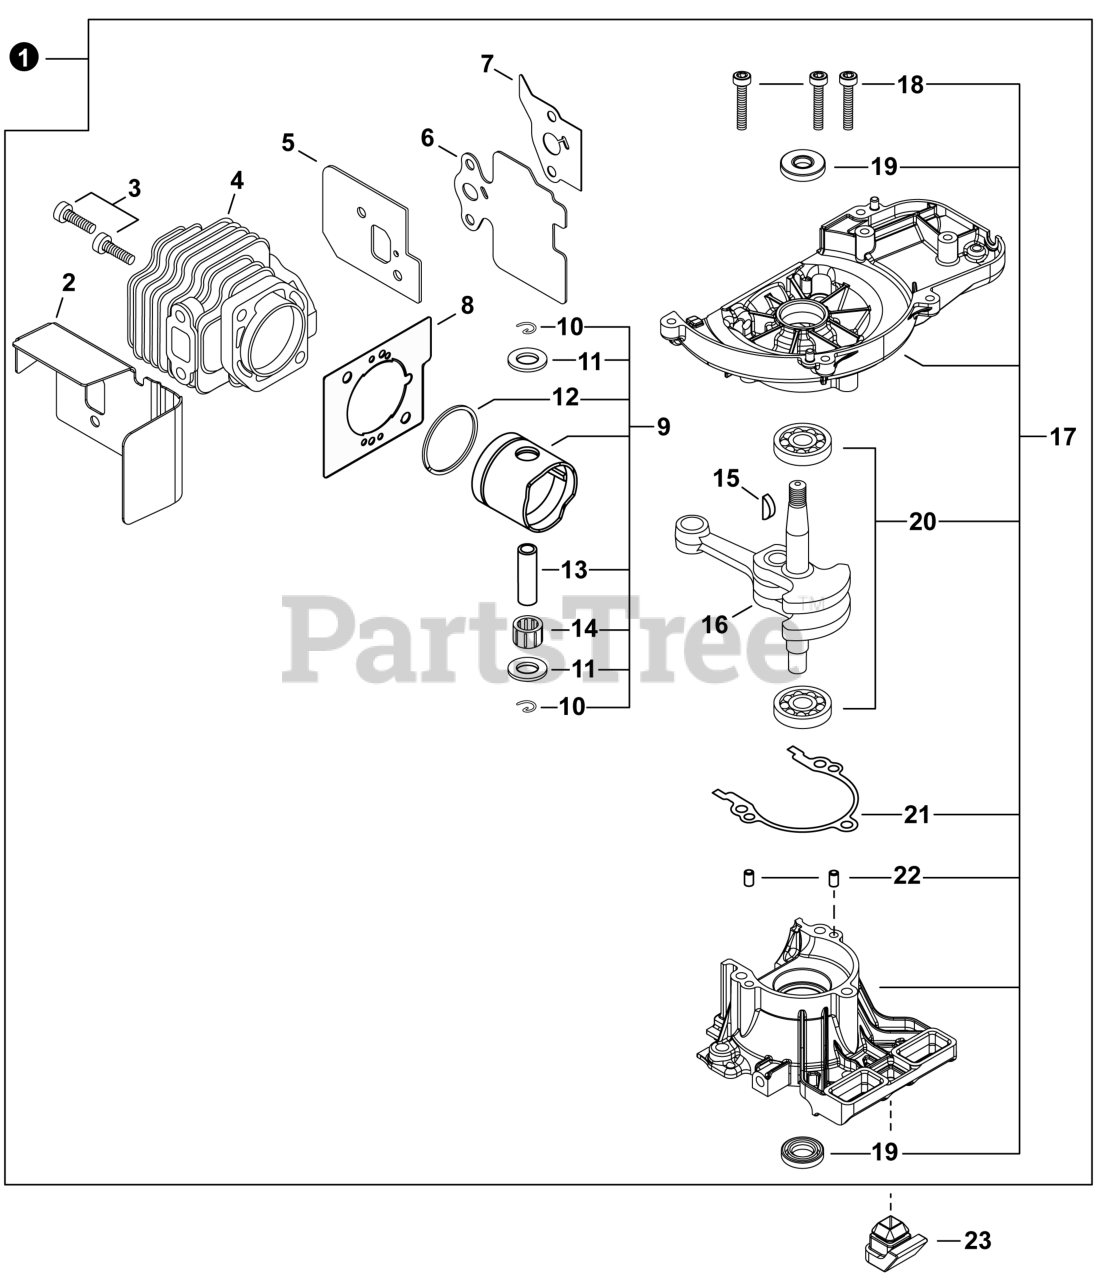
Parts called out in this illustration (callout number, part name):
1	SHORT BLOCK
2	HEAT SHIELD, EXHAUST
4	CYLINDER
5	GASKET, INTAKE
6	HEAT SHIELD, INTAKE
7	GASKET, INTAKE
8	GASKET, CYLINDER
9	PISTON KIT
10	RING, SNAP
11	WASHER, THRUST
12	RING, PISTON
13	PIN, PISTON 8
14	BEARING, NEEDLE
15	KEY, WOODRUFF
16	CRANKSHAFT ASSY
17	CRANKCASE KIT
18	BOLT 5×28
19	SEAL, OIL
20	BEARING, BALL
21	GASKET, CRANKCASE
22	PIN, LOCATING 4×8
23	CUSHION
